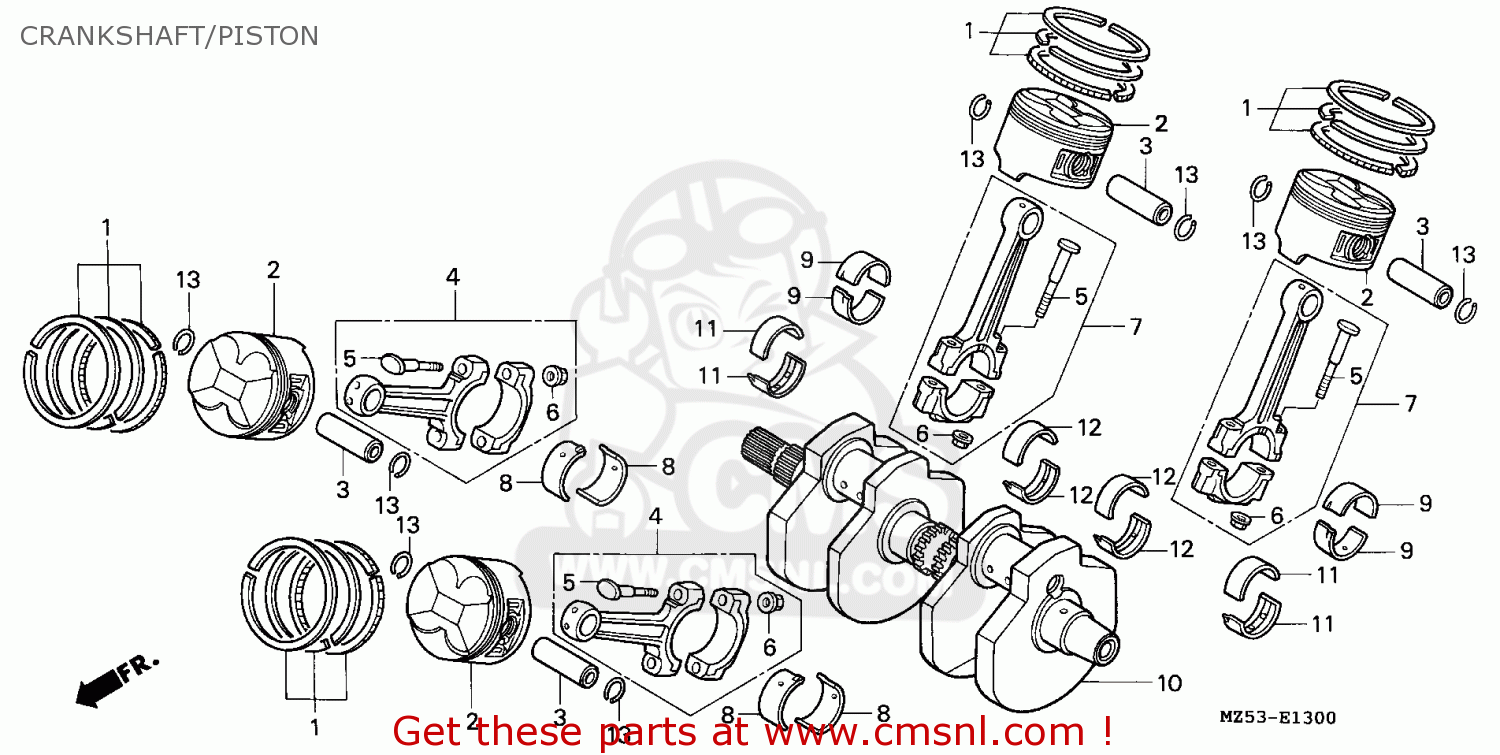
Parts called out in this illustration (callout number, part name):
1	RING SET,PISTON
2	PISTON
3	PIN,PISTON
4	CONNROD ASSY,FRON
5	BOLT,CONN-ROD
6	NUT,CONNECTIONG R
7	CONNROD ASSY,REAR
8	BEARING A,FR.CONN
9	BEARING A,RR.CONN
10	CRANK SHAFT COMP
11	BEARING A,CRANKSH
12	BEARING A,CRANKSH
13	CLIP,PISTON PIN
